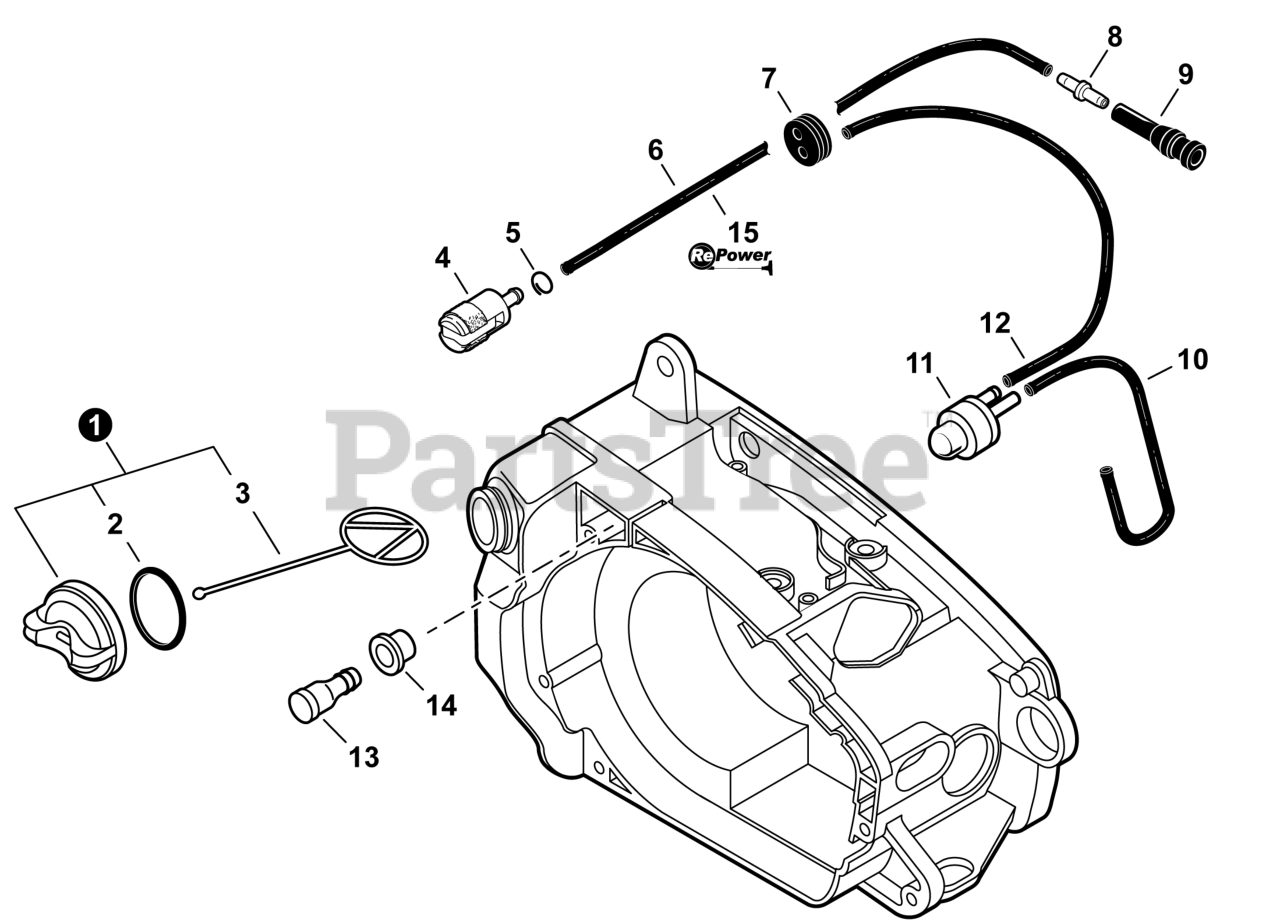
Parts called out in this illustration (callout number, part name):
1	CAP ASSY, FUEL - ORANGE
3	FUEL CAP CONNECTOR (L=60MM)
4	FILTER, FUEL
5	CLIP 6 MM
6	PIPE, FUEL 3×5×210 BLACK
7	GROMMET, FUEL
8	CONNECTOR, PIPE
9	PIPE, FUEL
10	PIPE 2.4×5×153
11	BULB, PURGE
12	PIPE 2.4×5×258
13	VENT ASSY
14	GROMMET, FUEL
15	BULK PIPE - 3×5 MM BLACK (4 PIECES×2 M)
